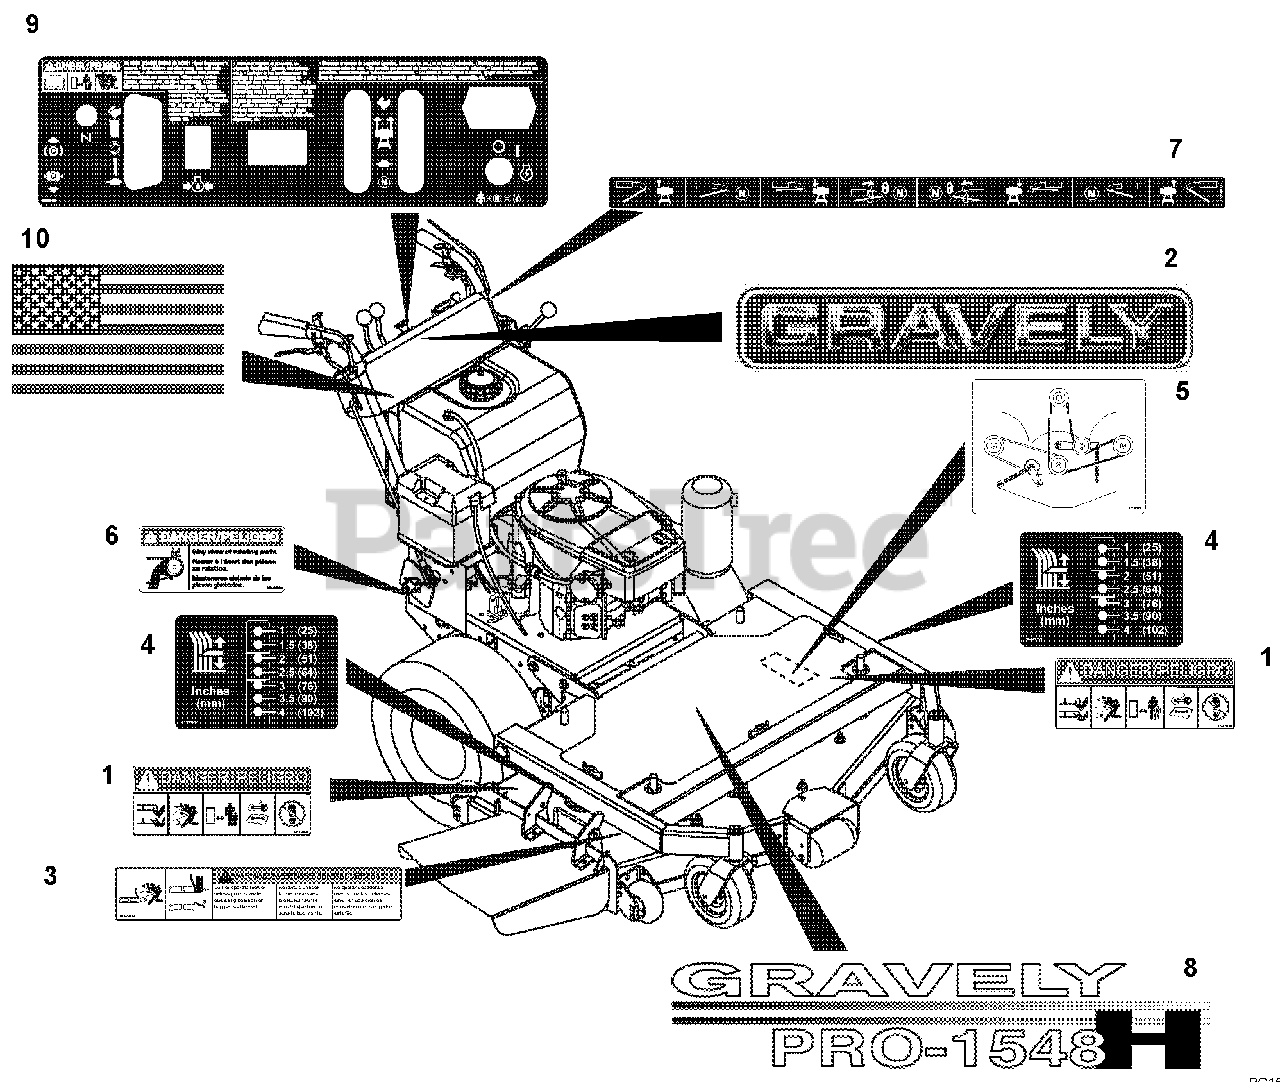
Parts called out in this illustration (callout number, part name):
1	Decal, Mower Pan Head Danger
2	Decal- 15" Gravely Logo
3	Decal, Warning (108, 126)
4	Decal-Height of Cut- Floating
5	Decal-Belt Diagram-3 Spindle
6	Decal-Danger-Belt Rotating
7	Decal, Steer Levers (108, 126)
8	Decal-Pro 1748H (108, 125)
9	Decal, Control (108, 126)
10	Decal, American Flag
